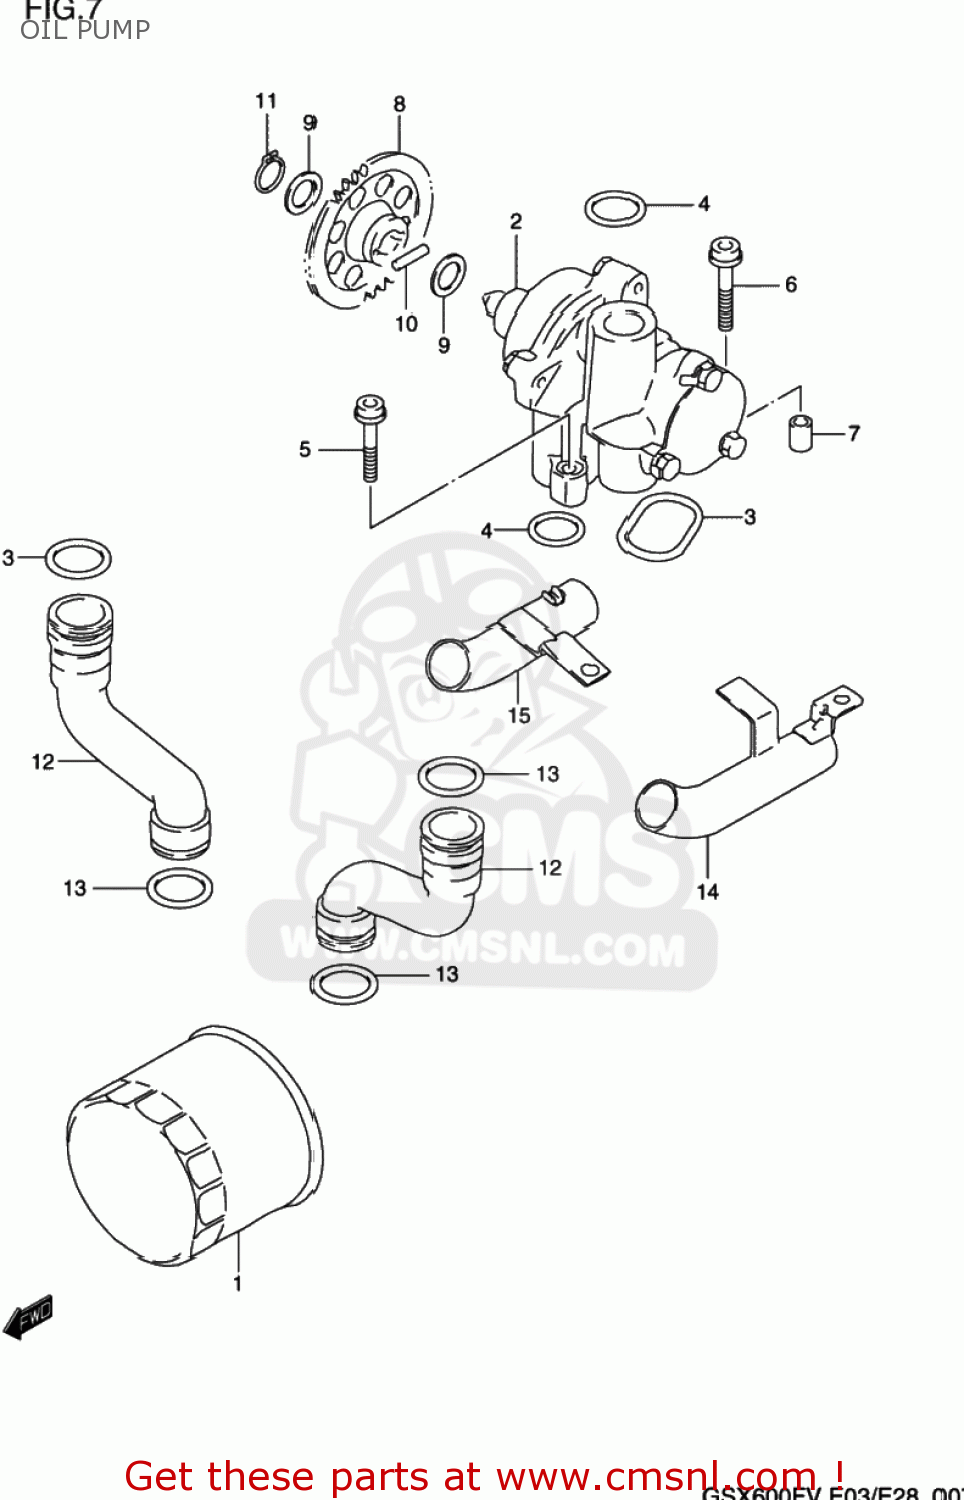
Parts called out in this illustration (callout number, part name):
1	FILTER ASSEMBLY,ENGINE OIL
2	PUMP ASSY,OIL
3	O RING,OIL PUMP
4	O RING(D:3.2,ID:17.8)
5	BOLT
6	BOLT
7	PIN
8	GEAR,OIL PUMP DRIVEN(NT:37)
9	SHIM
10	PIN(5X18)
11	CIRCLIP,12 MM
12	PIPE,OIL OUTLET
13	O RING(D:3.7,ID:21.7)
14	PIPE,OIL OUTLET UNDER,L
15	PIPE,OIL OUTLET UNDER,R
